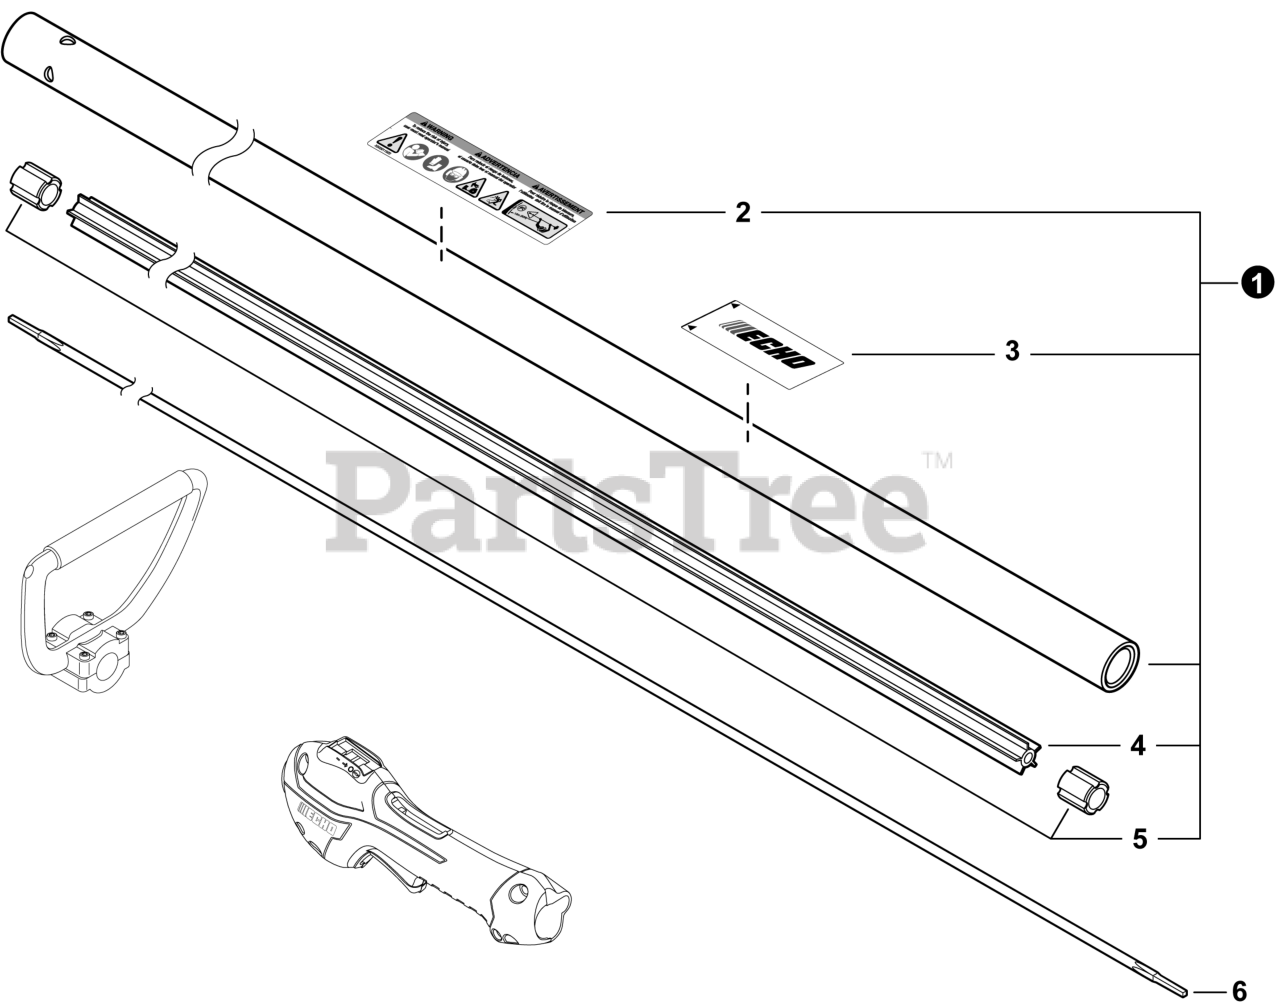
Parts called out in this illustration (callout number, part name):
1	MAIN PIPE ASSY
2	LABEL - CAUTION ISO
3	LABEL - HANDLE LOCATION
4	LINER, FLEXIBLE
5	STOPPER
6	DRIVESHAFT - FLEXIBLE
